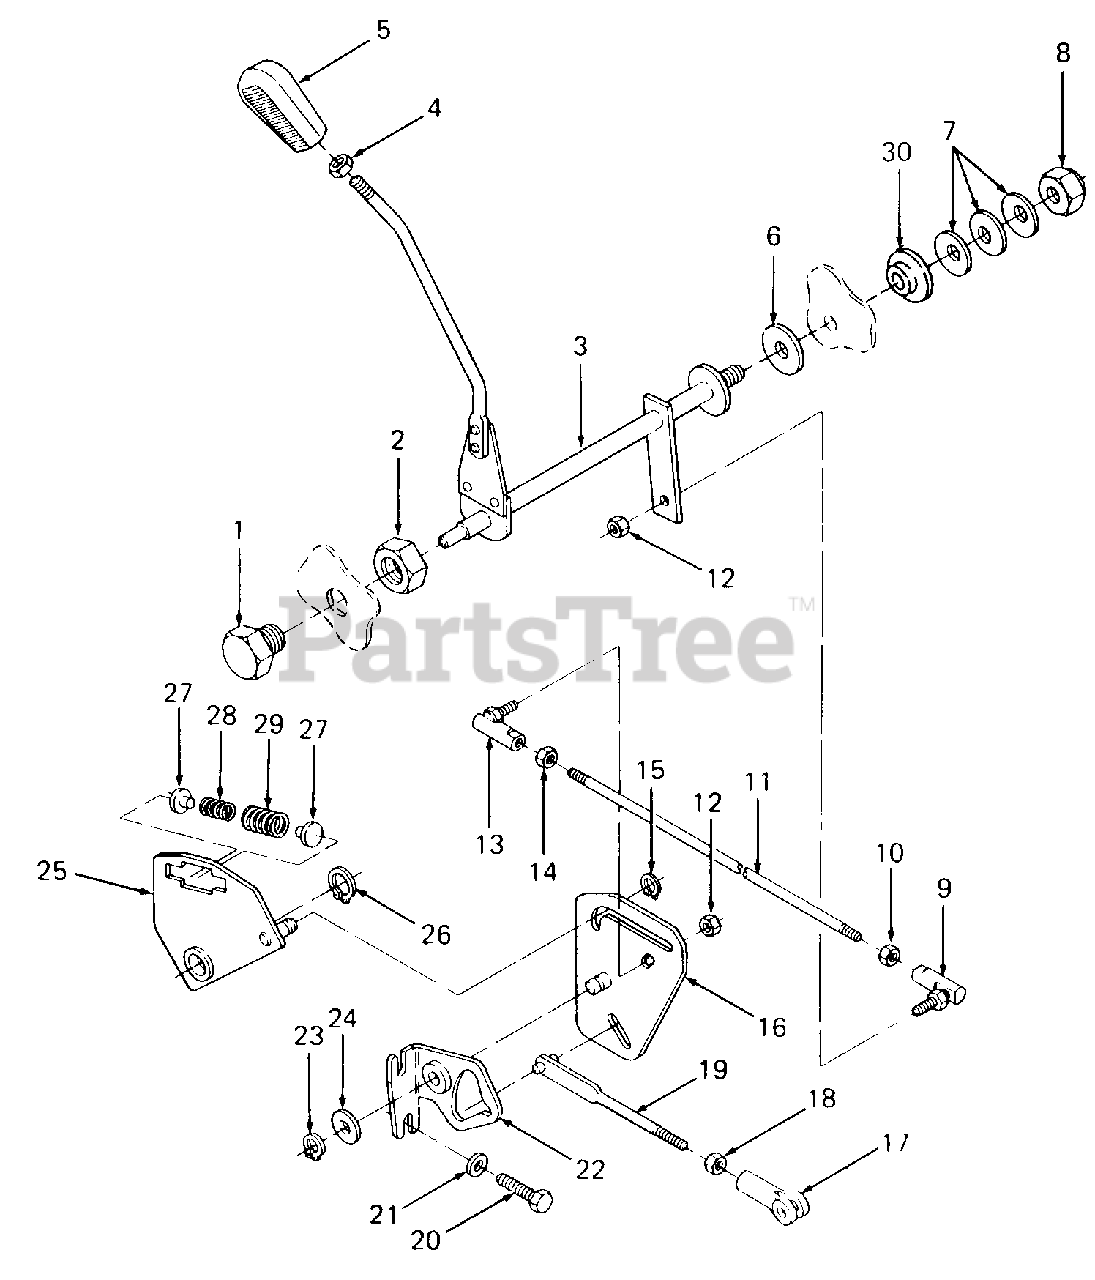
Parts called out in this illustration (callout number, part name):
1	Screw, Rockshaft Bearing, 3/4-16 X .75 Lg
2	Nut, Hex Jam, 3/4-16 GR5
3	Shaft Assy, Cross
4	Nut, Hex Jam, 3/8-16 GR5
5	Knob, Speed Control
6	Disc, Friction
7	Washer, Bell
8	Nut, Hex Top Lock, 1/2-20
9	Ball Joint, 5/16-24
10	Nut, Hex Jam, 5/16-24
11	Rod, Connecting
12	Nut, Hex Patch Lock, 5/16-24
13	Ball Joint, 5/16-24 LH Trd
14	Nut, Hex Jam, 5/16-24 LH Trd
15	Ring, Retaining, .375
16	Cam, Control
17	Clevis Adjustment
18	Nut, Hex Jam, 3/8-24 GR5
19	Rod, Control
20	Screw, Hex Cap, 3/8-16 X 1.5 Lg GR5
21	Washer, Flat, .385 X .87 X .06 Thk HDN
22	Bracket, Cam Pivot
23	Ring, Snap, .500
24	Washer, Flat, .510 X 1.0 X .060 Thk
25	Plate Assy, Damper Spring
26	Ring, Snap, .625
27	Pin, Spring Guide
28	Spring, Compression
29	Spring, Compression
30	Spacer, Shouldered
